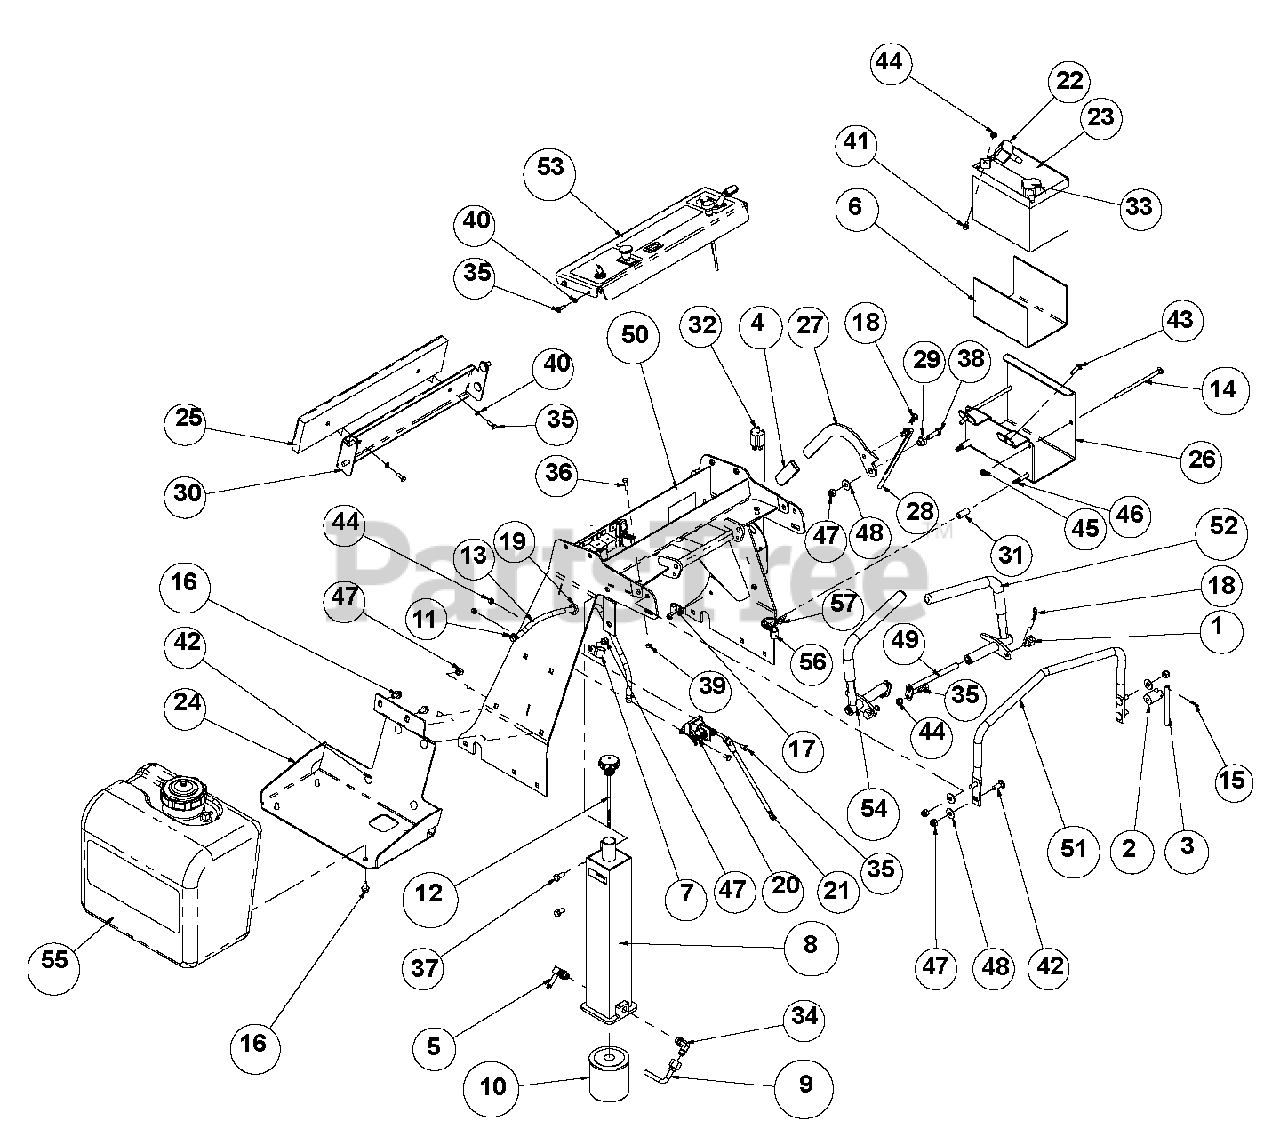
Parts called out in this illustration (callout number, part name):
1	Swivel Adjuster
2	Base, Lock Lever Y
3	Lever, Lock Y
4	Grip, PVC .250 x 1.00 x 3.63
5	Fitting, 90 9/16 MOR x 3/8 Hose
6	Strip, Battery Insulator
7	P-Clip, .750 Insulated
8	Reservoir, Hydraulic S/O
9	Elbow, Fitting
10	Filter, Oil
11	Clamp, Fuel Line
12	Cap, Filler Oil
13	Hose, .25 Low-PERM Bulk Gas
14	Bolt, 5/16-18 x 6.00 CRG 2 Y
15	Pin, Spring
16	Screw, Hex, FL,JDS123, M8 x 1.25 x 16
17	P-Clip, .500 Insulated
18	Pin, Hair .091 x 1.63 5/16-1/2 Y
19	Grommet, Round Rubber .625 x .19
20	Solenoid, 12 V Starter
21	Cable, 12" Starter
22	Cable, Battery Starter - 48"
23	Battery, 12V-U1-CCA270 Min
24	Bracket, Fuel Tank Mounting
25	Pad, Thigh
26	Tray, Battery
27	Lever, Brake
28	Link. Brake Y
29	Bushing, Brake Pivot Y
30	Weldment, Thigh Pad Bracket
31	Bushing, .364 x .540 x 1.250 Y
32	Switch, NO-NO-NC Grey Plunger
33	Cable, Battery Negative 30"
34	Fitting, 90 9/16 MOR x 9/16 MJIC
35	Bolt, Hex .25-20 x .75 Grade 5
36	Bolt, Hex .25-20 x 1.00 Grade 5
37	Bolt, Hex .38-16 x .75 Grade 5
38	Bolt, Hex .38-16 x 1.25 Grade 5
39	Nut, Hex .25-20
40	Washer, .250 Med. Spring Lock Y
41	Bolt, 1/4-20 x .625 WSH Y
42	Bolt, 3/8-16 x 1.00 CRG 5 SN Y
43	Bolt, 5/16-18 x 1.00 CRG 2 Y
44	Locknut, 1/4-20 Whiz Y
45	Locknut, 5/16-18 Nyloc Y
46	Bolt, 5/16-18 x 2.00 Round Head Square Neck 5 Y
47	Locknut, 3/8-16 Nyloc Y
48	Washer, .375 REG Flat Y
49	Weldment, Pin and Lock
50	Gravely Console With Decals
51	Handle, Support
52	LH Control Lever W/Grip
53	Assembly, Control Panel w/Decals (switches sold seperately)
54	RH Control Lever W/Grip
55	Tank, Fuel Assembly
56	P-Clip, .50 Insulated
57	Cable Tie .15 x 8.50
